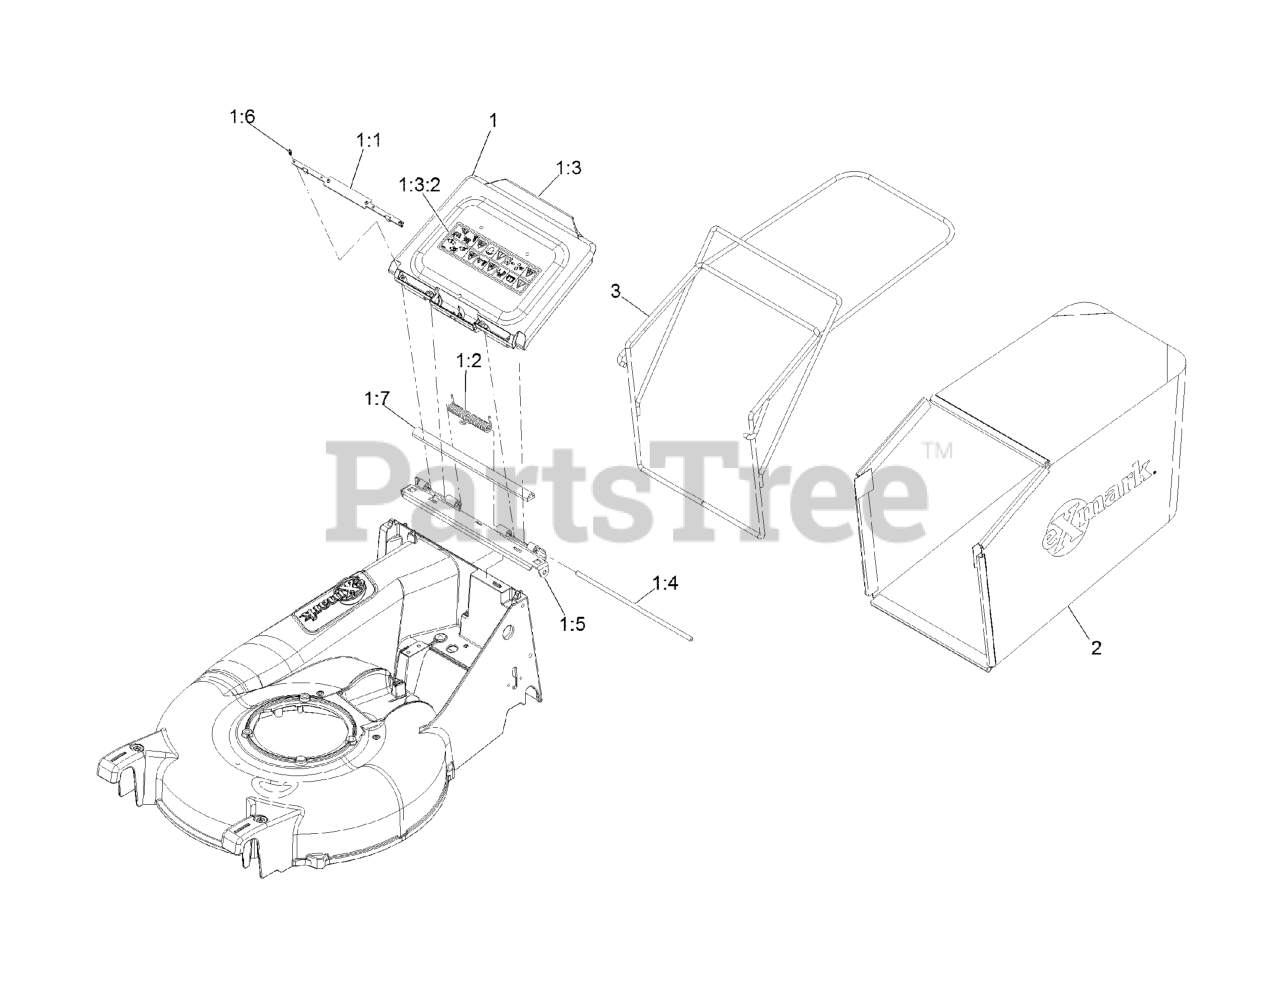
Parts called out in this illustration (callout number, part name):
1	DOOR ASM
1:1	X-REF 126-2628-03
1:2	SPRING-PLASTIC DOOR
1:3	ASM-DOOR & DECAL
1:3:2	DECAL-WARNING
1:4	PIN-DOOR PIVOT
1:5	X-REF TO 126-2636-03
1:6	SCR,TAP,6-19X7/16,PHPH, S
1:7	SEAL-EPDM FOAM BULB
2	BAG-GRASS EC21
3	WLD-BAG FRAME
